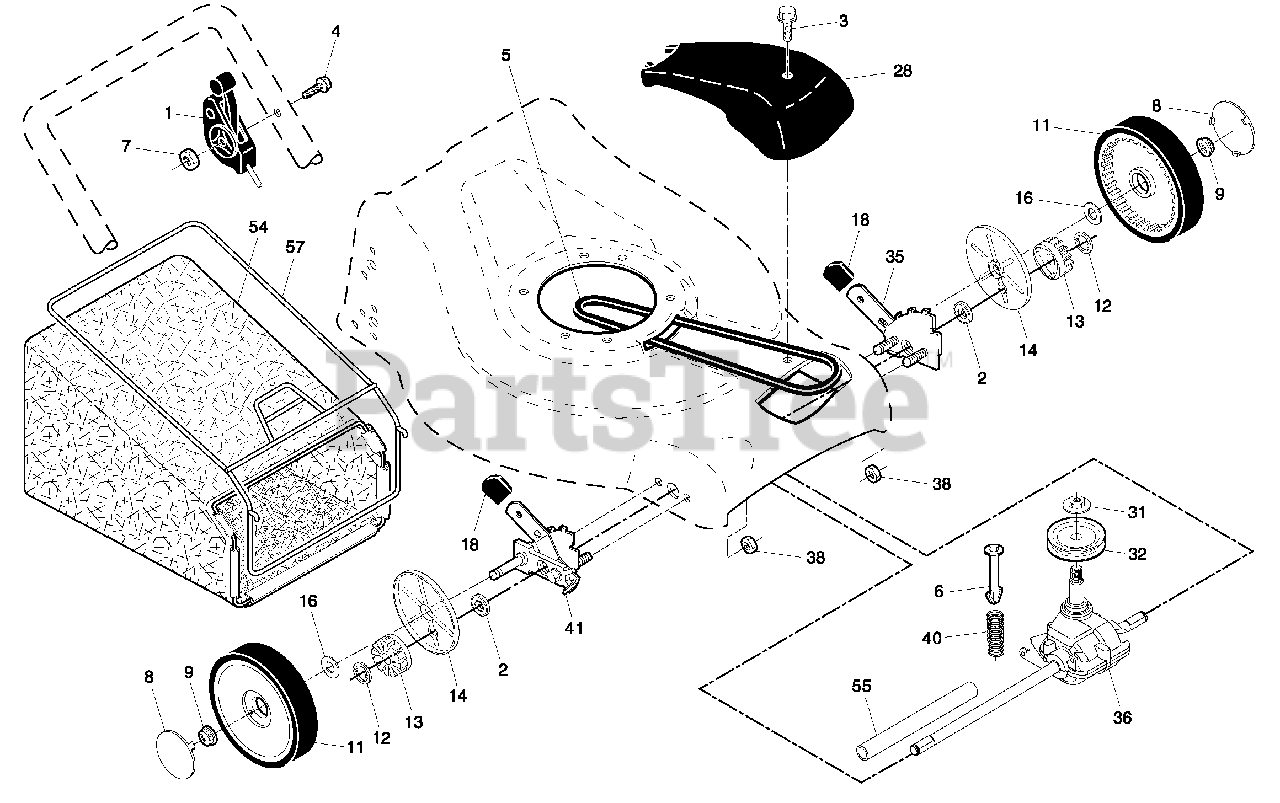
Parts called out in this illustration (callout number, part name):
1	Upper Handle
2	Lower Handle
3	Control Bar
4	Engine Zone Control Cable
5	Handle Bolt
6	Handle Knob
7	Hairpin Cotter
8	Wire Tie
9	Kit, Rear Door
10	Pop Rivet
11	Support Bracket, LH
12	Support Bracket, RH
13	Screw 1/4-20 x 5/8
14	Handle Bracket Assembly, LH
15	Handle Bracket Assembly, RH
16	Spring, Rear Door, LH
17	Spring, Rear Door, RH
18	Keps Locknut 1/4-20
19	Rope Guide
20	Rear Skirt
21	Hinge Screw 1/4-20 x 1-1/4
25	Screw, Hex Head, Threaded, Rolled 3/8-16 x 1-1/8
26	Nut, Hex, Flangelock 3/8-16
27	Wheel & Tire Assembly, Rear, 14"
28	Bolt, Shoulder 5/16-18
30	Axle Arm Assembly, Rear, RH
31	Selector Knob
32	Selector Spring
33	Nut, Hex, Nylock 5/16-18
34	Axle Arm Assembly, Rear, LH
36	Bolt, Rear Door
37	Thread Cutting Screw w/Sems 5/16-18 x 3/4
38	Spacer
40	Mounting Bracket, Debris Shield
41	Screw, Debris Shield
43	Debris Shield
44	Kit, Housing
45	Danger Decal
46	Blade Adapter / Pulley
47	Blade, 21"
48	Hardened Washer
49	Helical Washer 3/8
50	Hex Head Machine Screw 3/8-24 x 1-3/8 Grade 8
51	Clamp, Cable
52	Screw, Cable Clamp
53	Screw, Hex Head 1/4-20 x 2-11/64
54	Throttle Control
59	Discharge Deflector
60	Hinge Bracket Assembly
61	Spring
62	Rod, Hinge
63	Locknut, Hex 1/4-20
64	Mulcher Door
65	O-Ring
66	Washer, Flat 3/8
67	Kit, Bushing, High Wheel
68	Bushing, Nylon, Black
68	Operator's Manual, English
68	Operator's Manual, French
68	Repair Parts Manual, English / French
